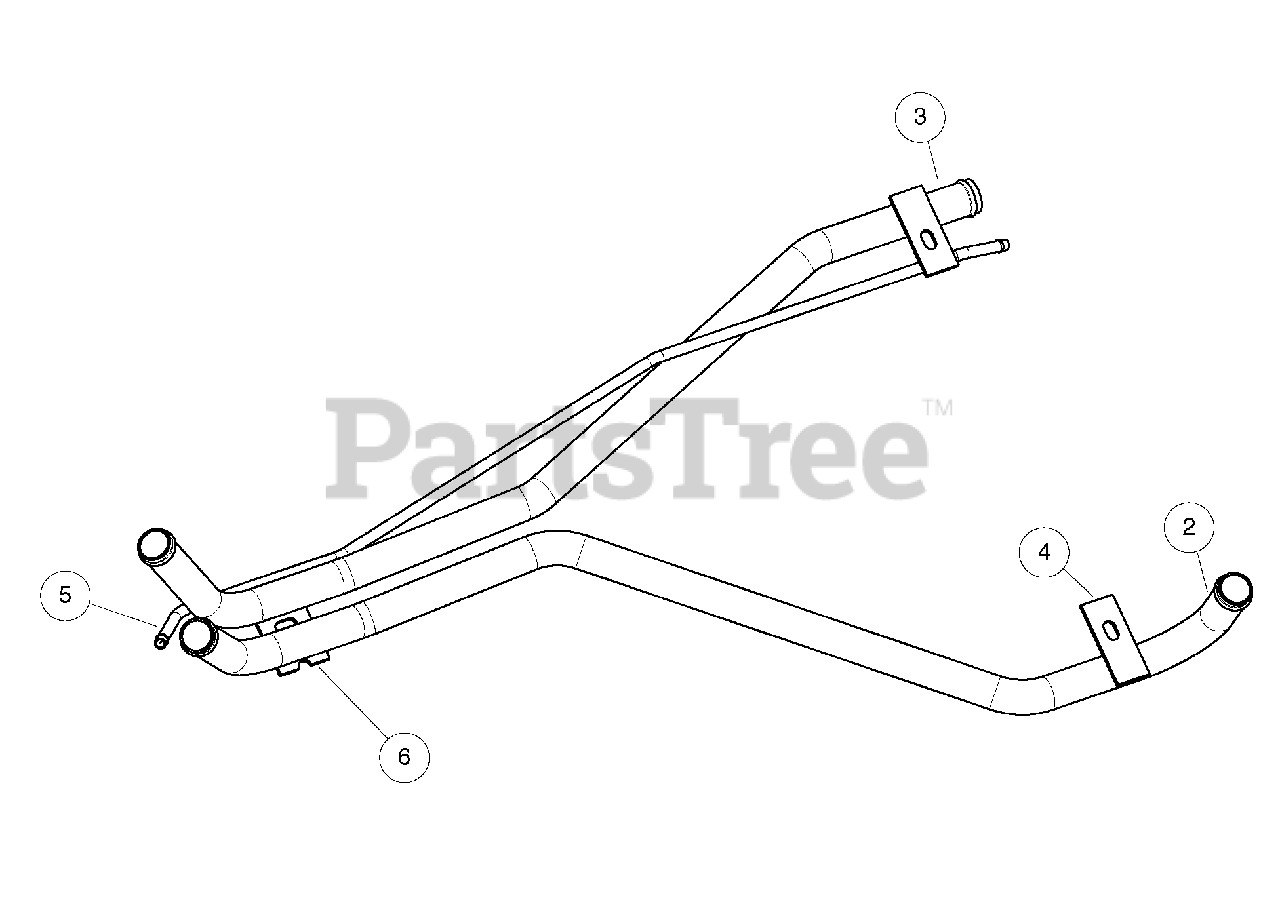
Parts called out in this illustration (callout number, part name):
1	Weldment, Group, Coolant Pipe
2	Pipe, Coolant Upper
3	Pipe, Coolant Lower
4	Tab, Rear Mntg, Coolant Pipe
5	Pipe, Vent, Coolant
6	Tab, Cooling Pipe Mount
